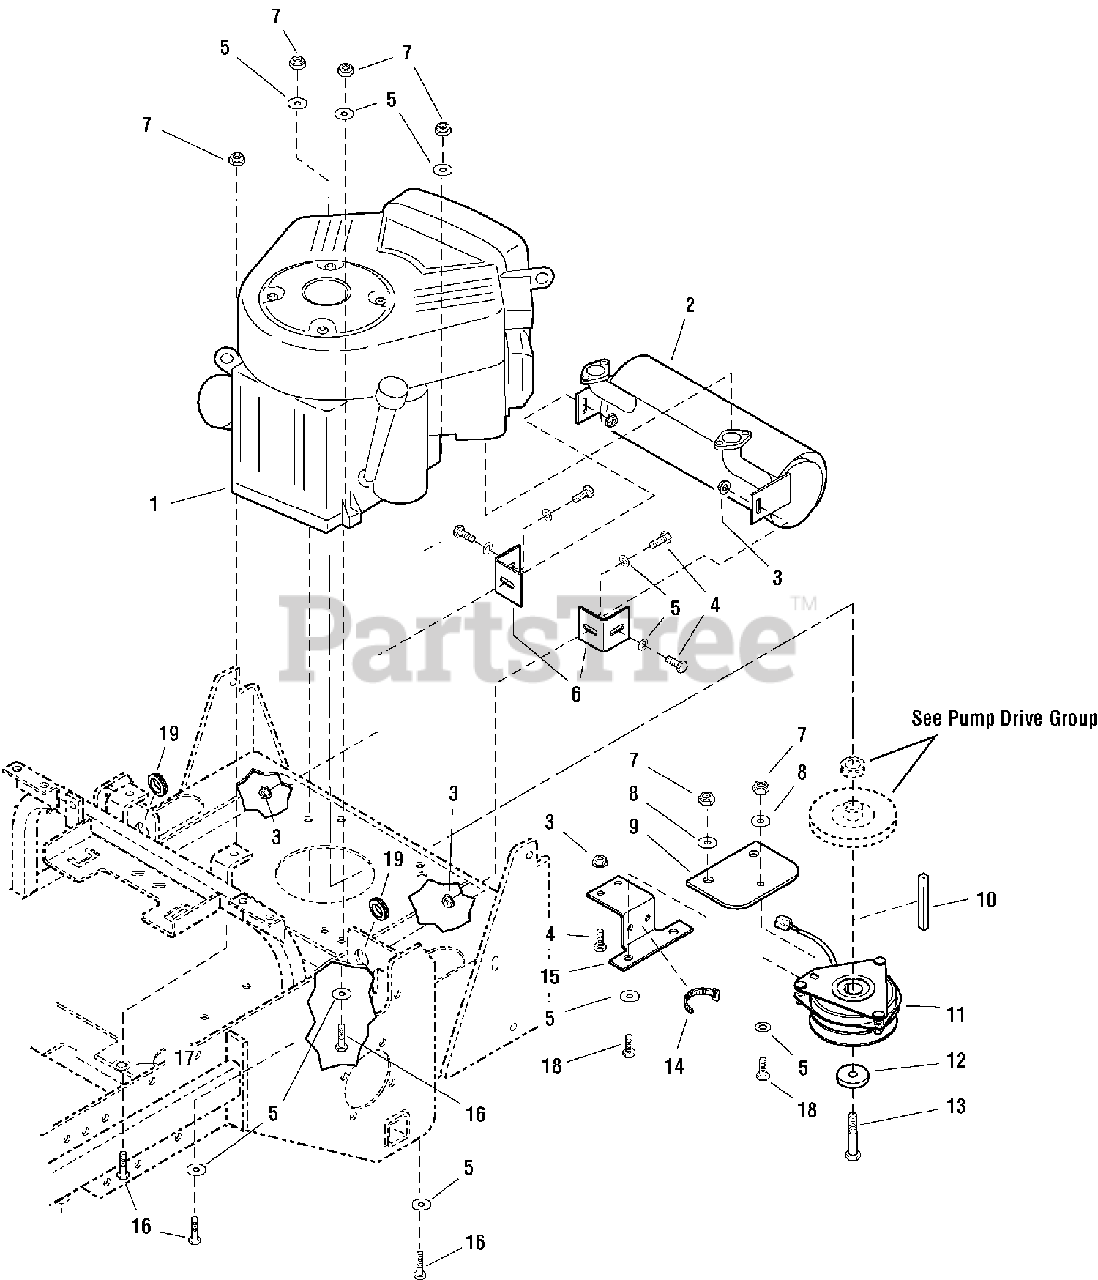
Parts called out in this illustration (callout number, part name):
1	* ENGINE, 20 HP BRIGGS, Mod. 358-777-0280-G1
2	MUFFLER
3	NUT, HEX SERRATED FLANGE, 5/16-18
4	BOLT, 5/16-18 X 3/4 GD5
5	WASHER, SAE, 5/16
6	BRACKET, MUFFLER SUPPORT (ORANGE)
6	BRACKET, MUFFLER SUPPORT (RED)
7	NUT, HEX NYLON LOCK, 5/16-18
8	WASHER, CLUTCH ANCHOR, 5/16 (N/A)
9	CLUTCH ANCHOR PAD
10	KEY, 1/4 SQ. X 2-1/4
11	CLUTCH, ELECTRIC
12	SPACER, .45 X 1.62 X .37
13	BOLT, CRANKSHAFT, 7/16-20 X 3-1/4"
14	TIE WRAP
15	CLUTCH ANCHOR (ORANGE)
15	CLUTCH ANCHOR (RED)
16	CAPSCREW, HEX HEAD, 5/16-18 X 1-3/4
17	WASHER, 5/16 INT TOOTH LOCK
18	CAPSCREW, HEX HEAD, 5/16-18 X 1
19	GROMMET, 3/4"
